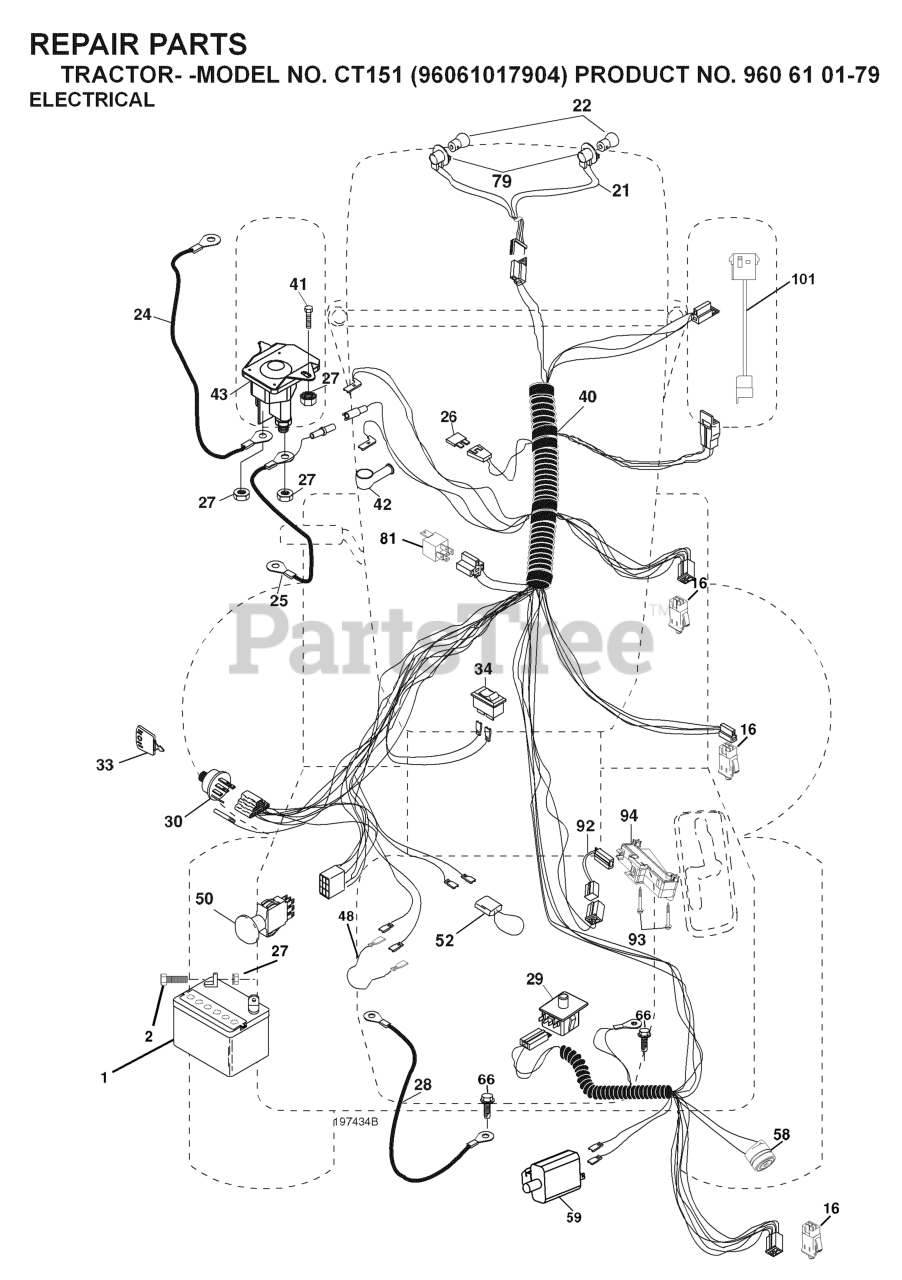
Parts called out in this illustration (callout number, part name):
1	BATTERY 12V .35 AMP
2	BOLT.HEX.1/4.X.3/4.DICHROMATE
16	SWITCH INTERLOOK PUSH-IN
21	HARNESS.LIGHT W/4152J BULBS
24	BATTERY CABLE GT
25	CABLE BATTERY
26	FUSE 20AMP
27	NUT
28	CABLE GROUND
29	SWITCH.SEAT.DP W/RAMPS
30	SWITCH.IGN.DELTA.W.LGH.ROS
33	KEY MLD GEN DELTA
40	RP HARNESS.IGN.ELECT.REG.CRD
41	BOLT
42	TERMINAL COVER
43	SOLENOID.W/BRASS.PLUNGER
48	ADAPTER.AMMETER
50	RP.PTO.SWITCH.8 TERMINAL.BLACK
52	WIRE PROTECTION LOOP
58	BUZZER
59	.WITCH.FULL BAGGER.INDICATOR
81	RELAY.ASSY.T
92	HARNESS.PIGTAIL.CONSLE
93	SCREW.PLASTITE
94	MODULE.REVERSE.ROS
101	PIGTAIL.MATNLK.NEW.HAR
